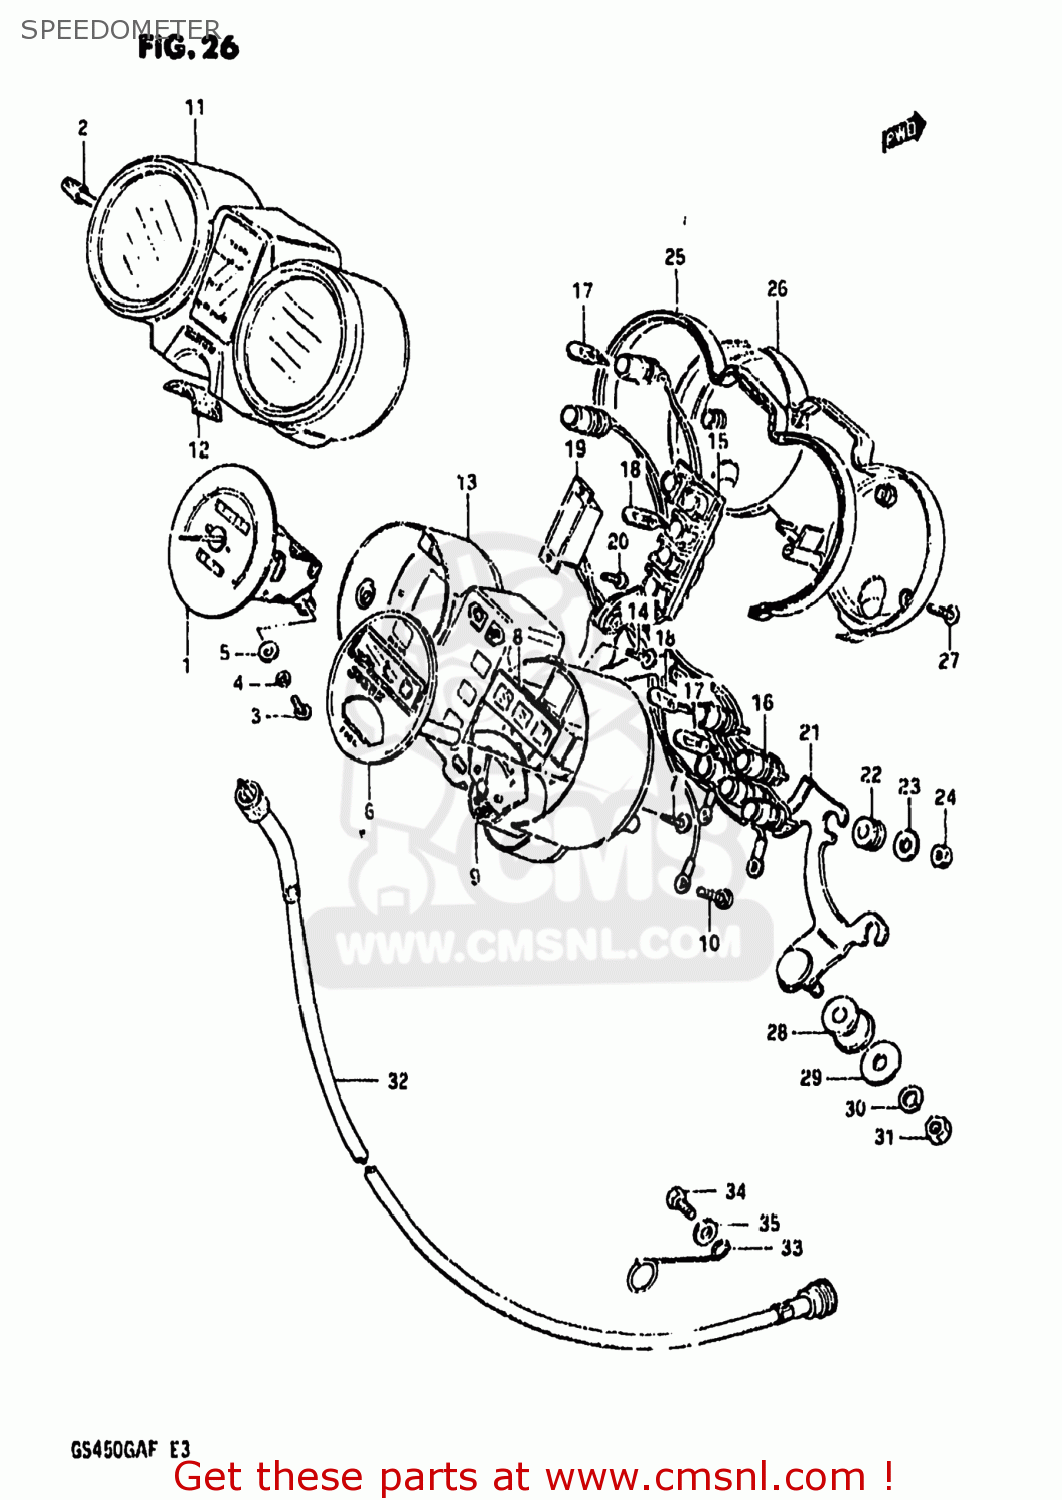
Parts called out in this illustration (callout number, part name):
1	METER,SPEEDOMETER (KM/MPH)
2	KNOB
3	SCREW 4X10
4	LOCK WASHER
5	WASHER
6	PLATE,PILOT PANEL NO.1
7	SCREW,GEAR INDICATOR
8	PLATE,PILOT PANEL NO.2
9	METER,FUEL
10	SCREW(3X22)
11	HOOD,METER
12	SEAL,IGNITION SWITCH
13	CASE,METER,INNER
14	SCREW
15	SOCKET,GEAR INDICATOR
16	SOCKET
17	BULB(12V3.4W,T10)
18	BULB(12V1.7W,T10,WB121)
19	WARNING LAMP,SIDE STAND
20	SCREW,GEAR INDICATOR
21	BRACKET,COMBINATION METER
22	CUSHION,METER
23	WASHER (5.5X16X1.2)
24	NUT
25	COVER,METER,UNDER
26	COVER,LWR
27	SCREW
28	CUSHION,METER BRACKET
29	WASHER (8.5X20X1.6)
30	WASHER,LOCK,8.
31	NUT ,8MM
32	CABLE ASSY,SPEEDOMETER
33	CLAMP,SPEEDOMETER CABLE
34	BOLT, UPPER
35	WASHER
